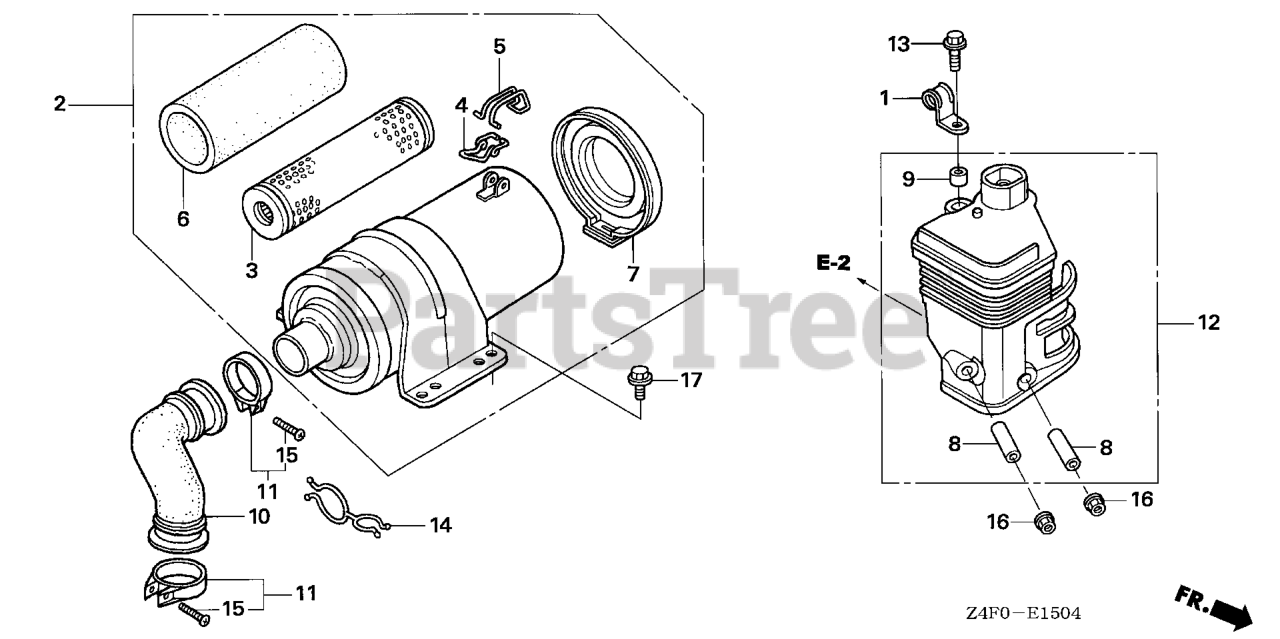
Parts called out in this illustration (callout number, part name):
1	CLIP B, TUBE
2	AIR CLEANER ASSY.
3	ELEMENT, AIR CLEANER
4	CLIP A, WIRE
5	CLIP B, WIRE
6	FILTER (OUTER)
7	COVER, AIR CLEANER
8	COLLAR, AIR CLEANER Use from Engine SN 1786085.
9	COLLAR B, AIR CLEANER
10	TUBE, AIR CLEANER CONNECTING
11	BAND, A/CLNR TUBE
12	ELBOW, AIR CLEANER
13	BOLT, FLANGE (6X12) (CT200)
14	CLIP, WATER HOSE
15	SCREW, PAN (4X20)
16	NUT, FLANGE (6MM)
17	BOLT, FLANGE (6X16) Use from Engine SN 2056820.
